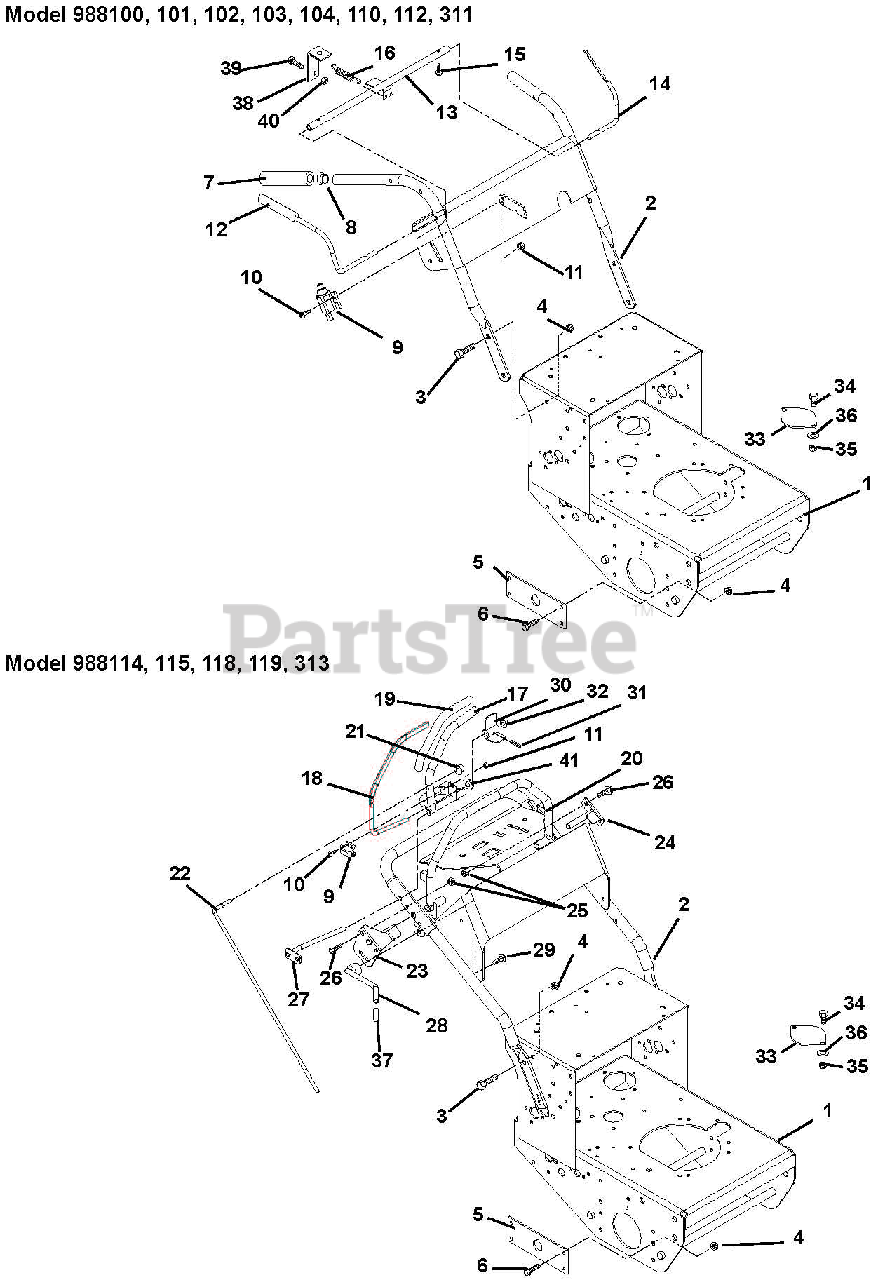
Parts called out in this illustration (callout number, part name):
1	Kit-Frame with Decals
2	Kit-Handlebar with Decals GR13
2	Kit-Handlebar with Decals GR15
2	Kit, Handlebar with Decals GE17
2	Kit, Handlebar with Decals GR13/15-Pro Steer
3	Bolt-Hex .38-16 x 1.00 Grade 5
4	Nut-Locking-Nylon .38-16
5	Plate, Support
6	Bolt-Hex .38-16 x 1.00 Grade 5
7	Grip, Handlebar
8	Caplug, Handlebar
9	Switch, Double Pole
9	Switch, Single Pole
10	Screw, Machine 10-24 x .75 Hex Washer Head
10	Screw-Machine 10-24 x .75 Hex Washer Head
11	Nut-Locking-Nylon 10-24 with Insert
12	Lever, Right Hand-Operator Presence
13	Weldment, Pivot Tube
14	Lever, Left Hand-Operator Presence
15	Screw-Tapping 8-32 x .50 Hex Washer Head
16	Spring-Tension .047 x .438 x 1.45
17	Weldment, Lever-Right Hand Speed Control
17	Weldment-Lever-Left Hand Speed Control
18	Lever- Operator Presence
19	Grip- Handlebar
20	Weldment- Speed Control Stop
21	Ring-Retaining-External .375 x .010
22	Rod, Steering
23	Weldment, Control Stop Limiter-Right Hand
24	Weldment, Control Stop Limiter-Left Hand
25	Nut-Locking-Top-Flange .31-18
26	Bolt-Hex .31-18 x 1.75 Grade 5
27	Weldment, Speed Control Pivot- Right Hand
27	Weldment, Speed Control Pivot- Left Hand
28	Lever- Control Stop Lock
29	Bolt-Round Head Square Neck .31-18 x .75 Grade 5
29	Bolt-Round Head Square Neck .38-16 x .75 Grade 2
30	Actuator, Switch
31	Pin-Roll .125 x .75
32	Nut-Push .312
33	Plate, Cover
34	Bolt-Hex .38-16 x .75 Grade 5
35	Nut-Locking-Flange .375-16
36	Washer-Flat-Steel .406 x .812 x .065
37	Grip, Hand Clutch Lever
38	Bracket, Brake Link
39	Bolt, Hex .25-20 x .75 Grade 5
40	Nut, Locking Nylon .25-20
41	Washer, Wave
